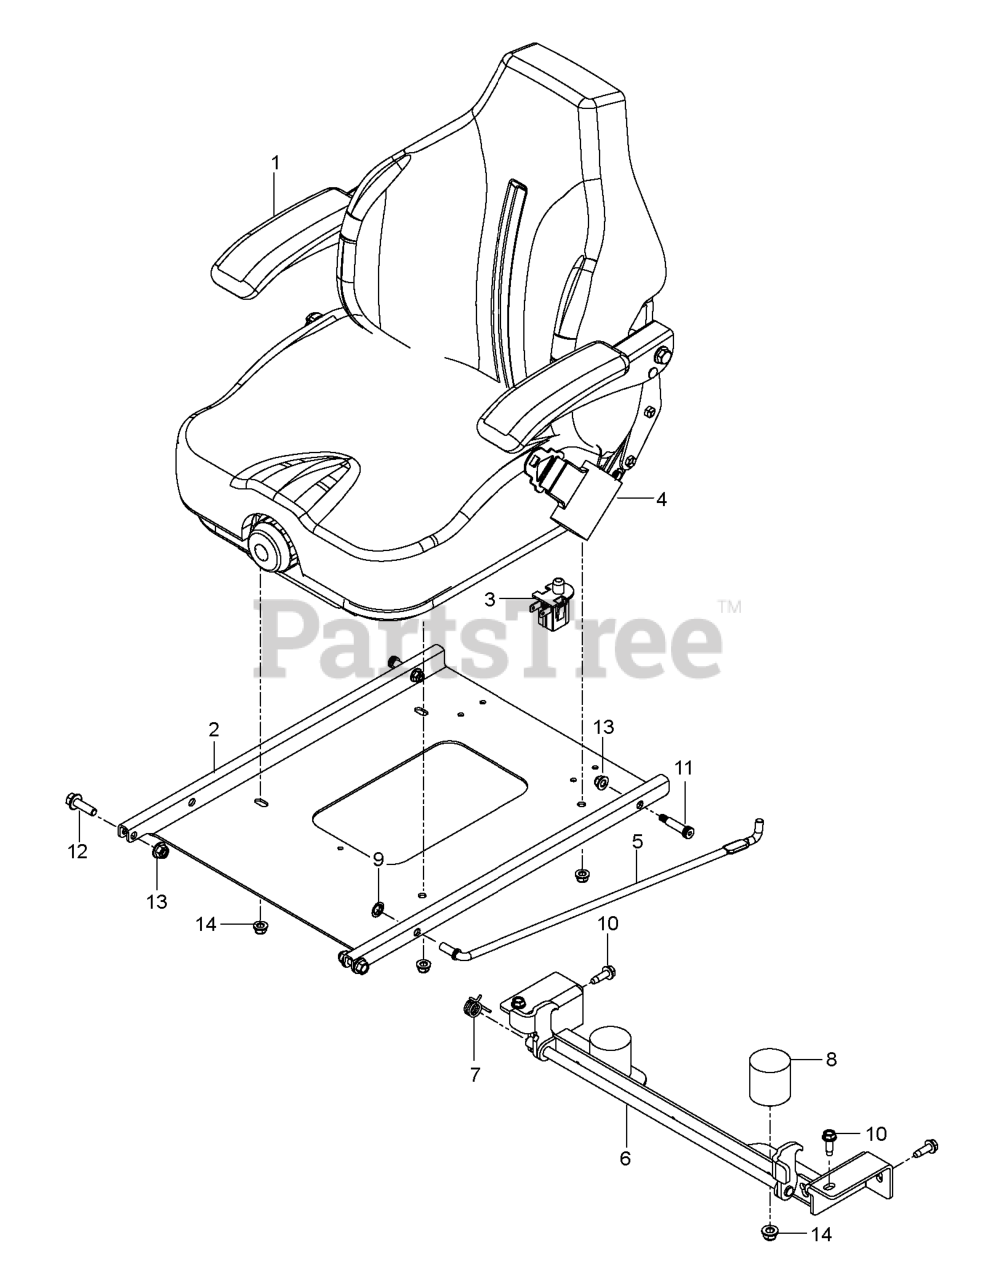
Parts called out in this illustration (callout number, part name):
1	SEAT.ASM.SUSPENSION.TRACK
2	PAN, SEAT, BLACK
3	SEAT SWITCH
4	SEAT BELT, RETRACTABLE
6	BRACKET.PNT.LATCH.SEAT.BUMPER
7	SPRING, TORSION
8	BUMPER, RUBBER
9	NUT 3/8 PALNUT RTNG BLK PHOS
10	RP BLT 5/16-18 X 1 THRD FORM D
11	BOLT, SHOULDER 3/8 X 1.25
12	HHFS 3/8-16 X 1.25 GD 5
13	NUT 3/8-16 HEX FLG NYLOC ZD
14	5/16-18 NYLOC FLANGE NUT
